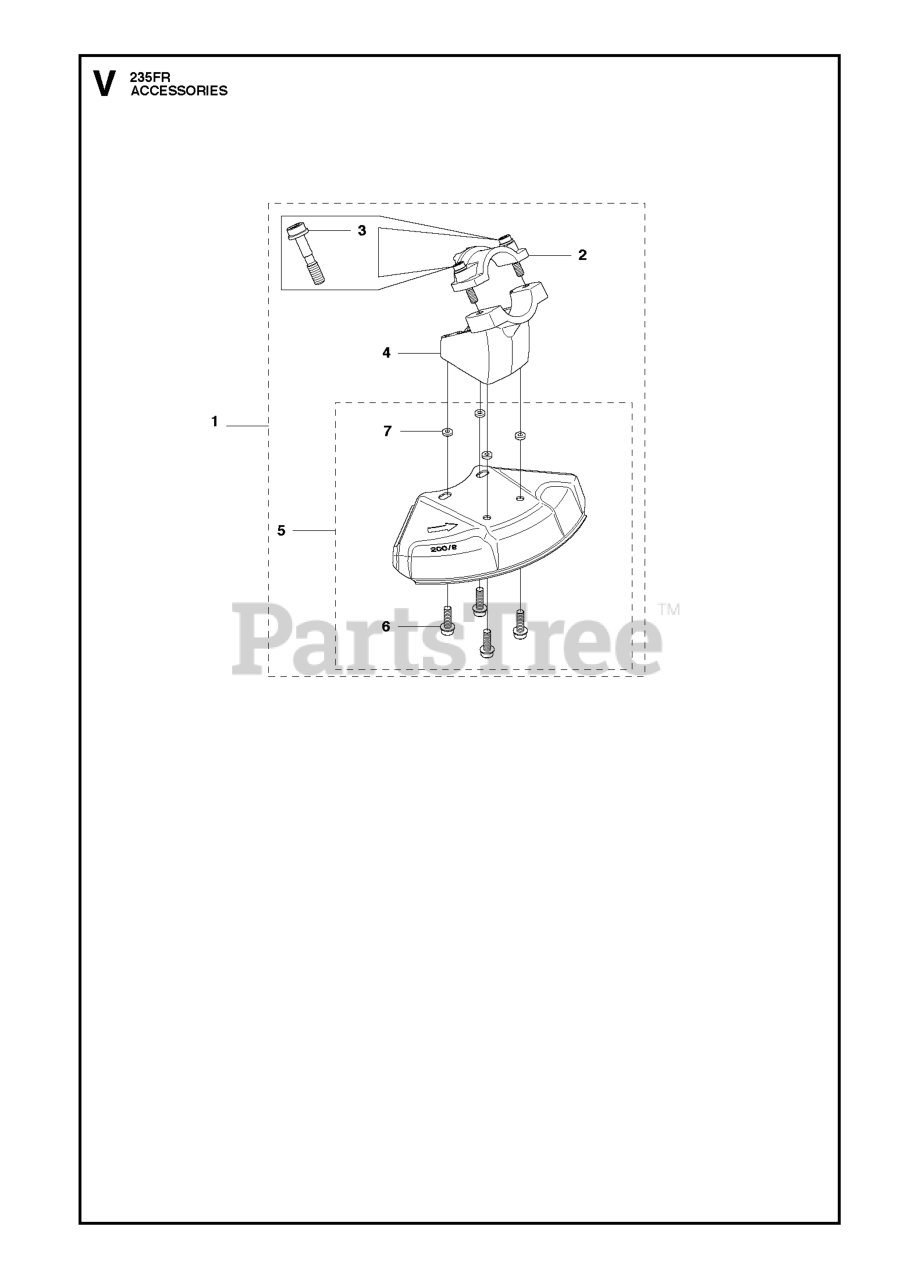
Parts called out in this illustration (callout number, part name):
1	ADAPTER
2	CLAMP
3	SCREW IHSCFMO
4	ADAPTER
5	BLADE GUARD
7	LOCKING NUT
